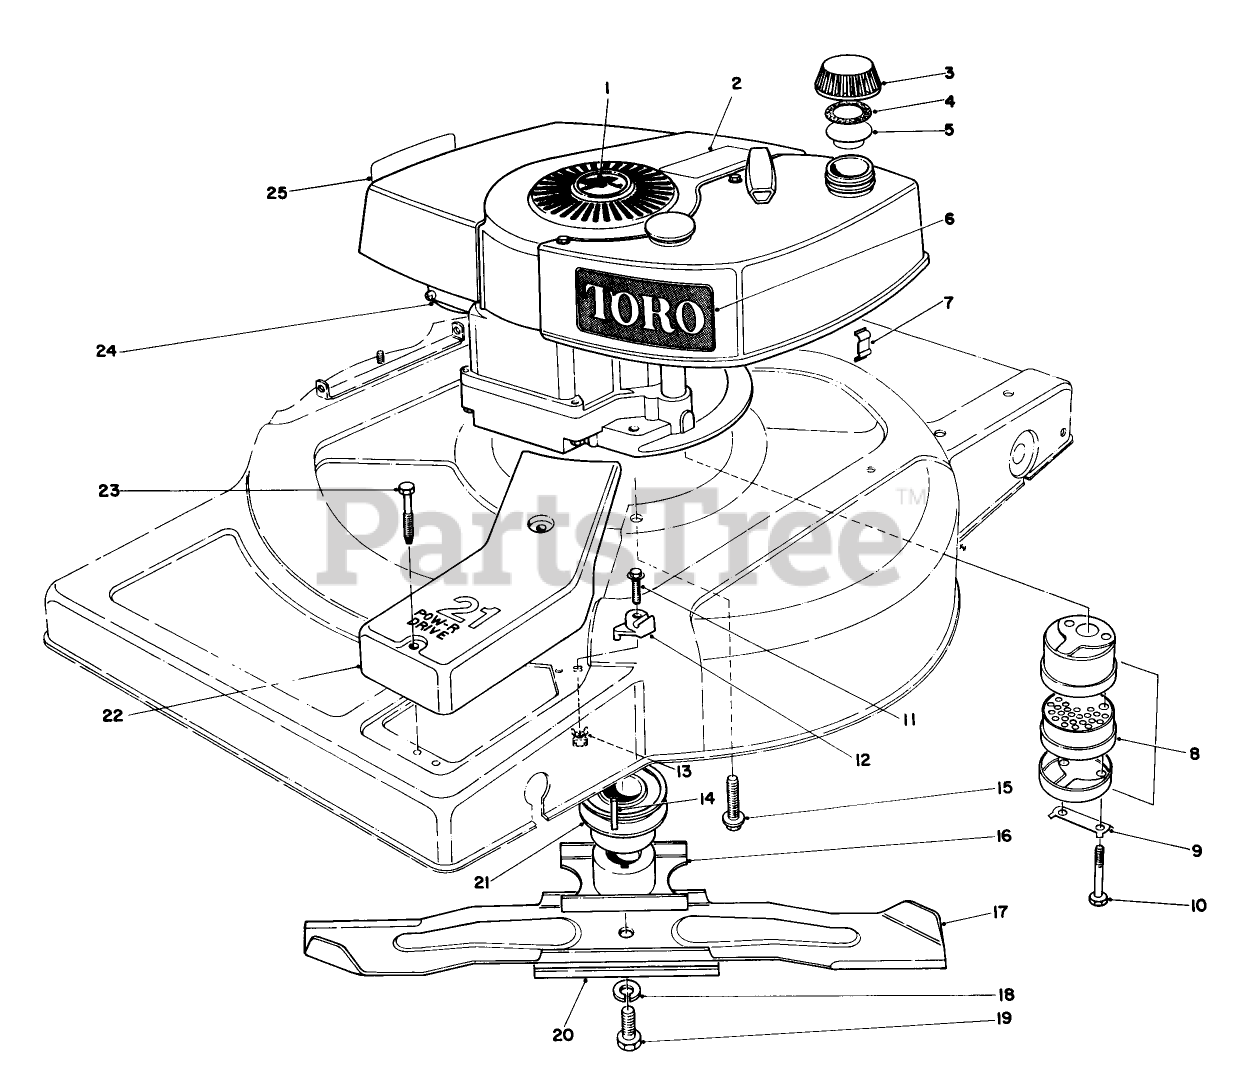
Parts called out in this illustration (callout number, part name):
1	PLUG BUTTON
4	GASKET
8	MUFFLER ASM
9	CLIP - LOCKING
10	SCREW-HH
14	KEY-SQUARE
18	WASHER-LOCK
23	SCREW-HWH
24	Engine
